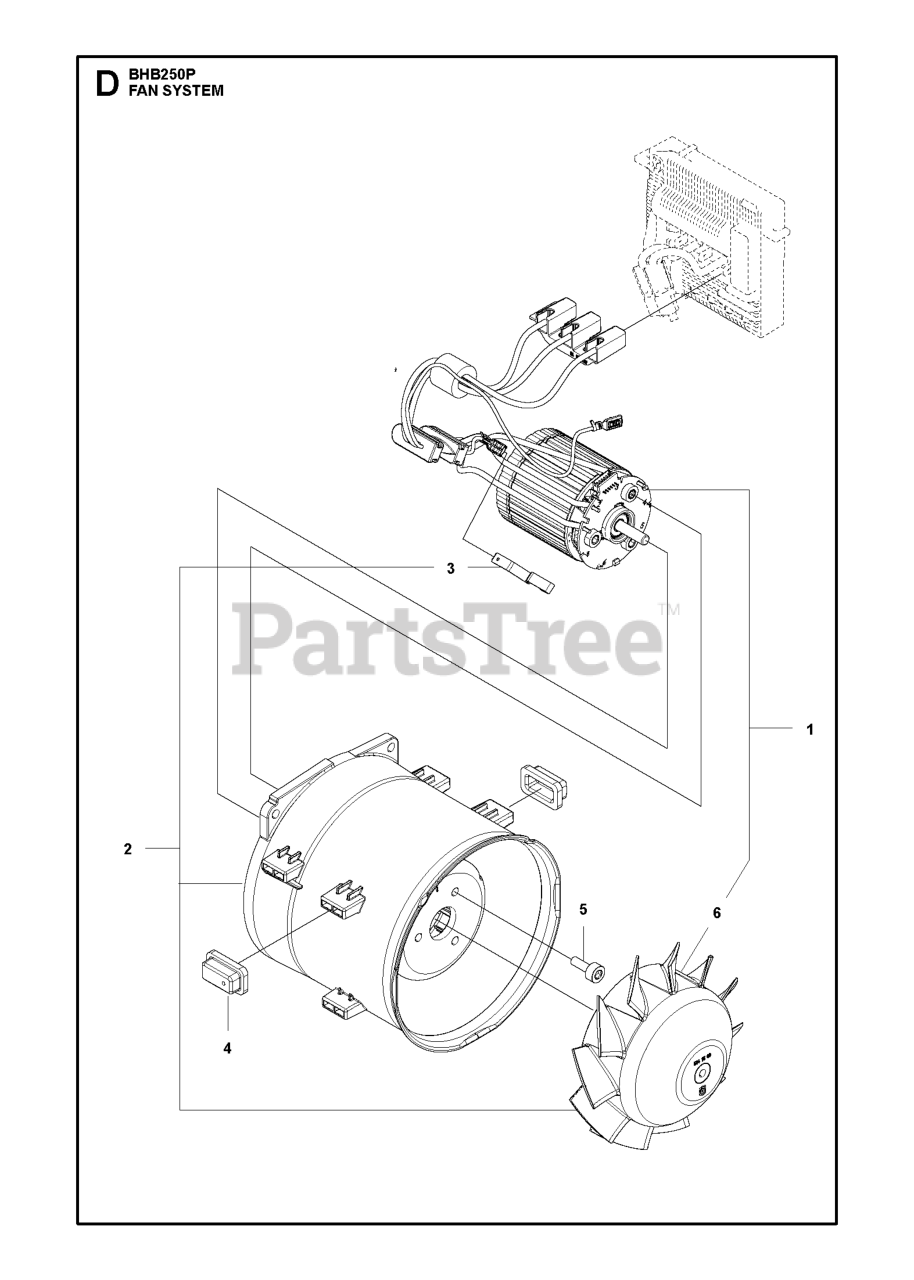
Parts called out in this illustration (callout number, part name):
1	MOTOR ASSY BLDC JOHNSON
2	KIT STATOR
6	ROTOR FAN
